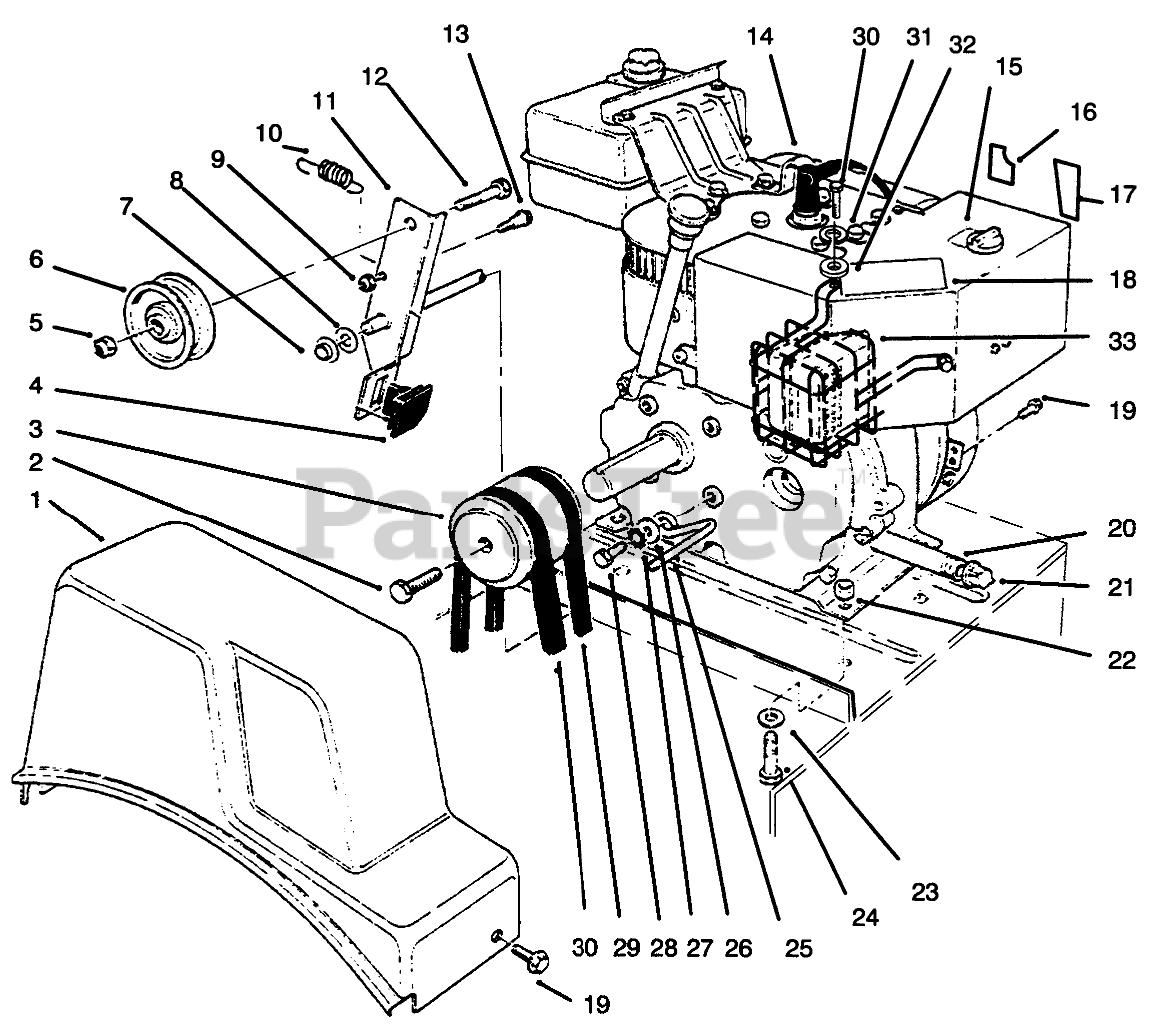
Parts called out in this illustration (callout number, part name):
1	COVER-BELT
2	SCREW-SPECIAL
3	PULLEY-ENGINE
4	PAD-BRAKE
5	NUT-LOCK, NI
6	PULLEY-IDLER
7	RETAINER-PUSH ON
8	WASHER-FLAT
9	NUT-LOCK, NI
10	SPRING
11	Auger Clutch (Incl. Ref. #4)
12	SCREW-HH
13	BOLT-SHOULDER
15	DECAL-CHOKE
16	DECAL-PRIMER
17	DECAL-THROTTLE
18	DECAL-WARNING, HOT SURFACE
19	SCREW-HWH
20	PIPE-NIPPLE
21	CAP-PIPE
22	NUT-LOCK, NI
23	WASHER-PLAIN
24	SCREW-HH
25	RETAINER-BELT
26	WASHER-LOCK
27	SCREW-HH
28	V BELT-3L, TRACTION
29	V-BELT
30	Screw
31	Washer-Lock
32	Washer-Flat
33	Guard-Muffler
